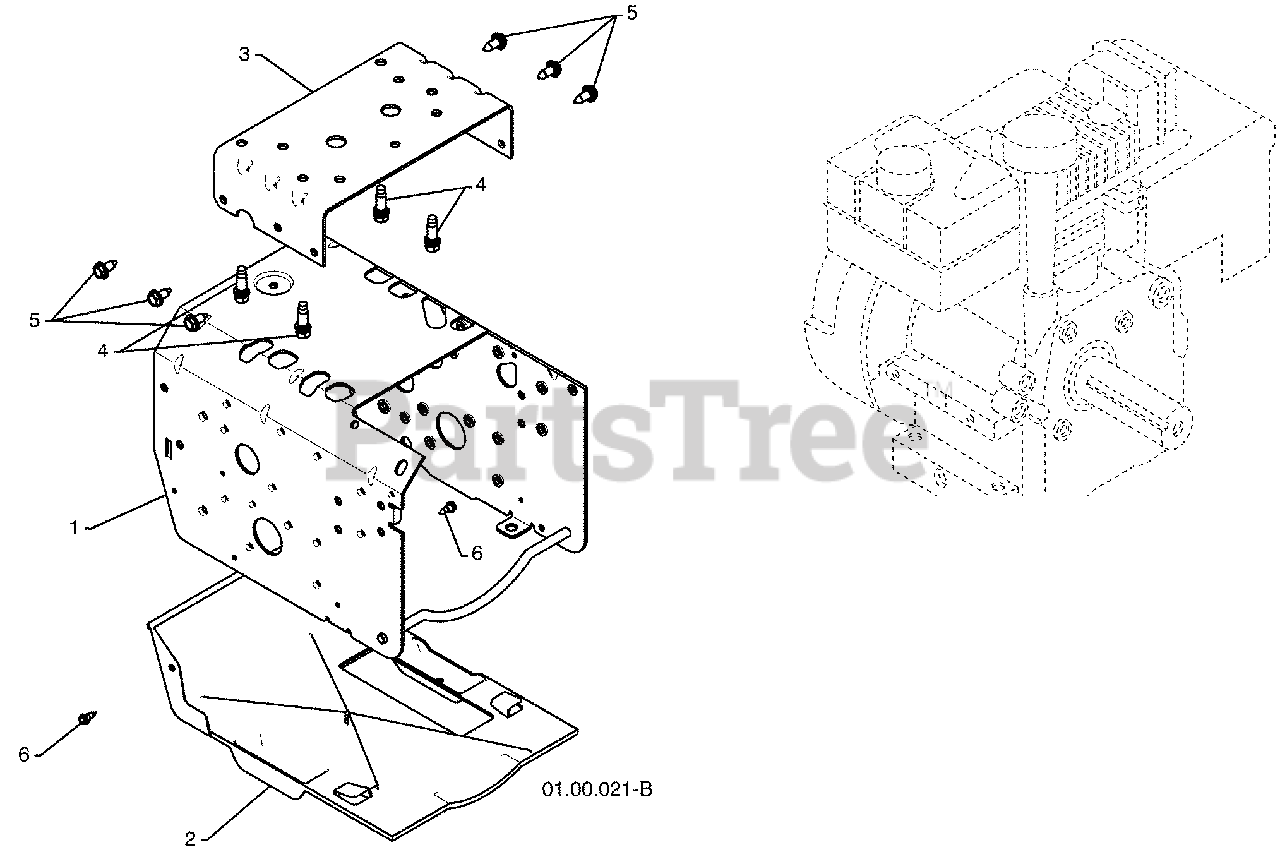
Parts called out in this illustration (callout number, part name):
2	BOTTOM PAN
3	ENGINE MOUNT PLATE
4	BOLT 3/8-16
5	SCREW 5/16-18 X .750
6	SCREW 10-24 X .625
